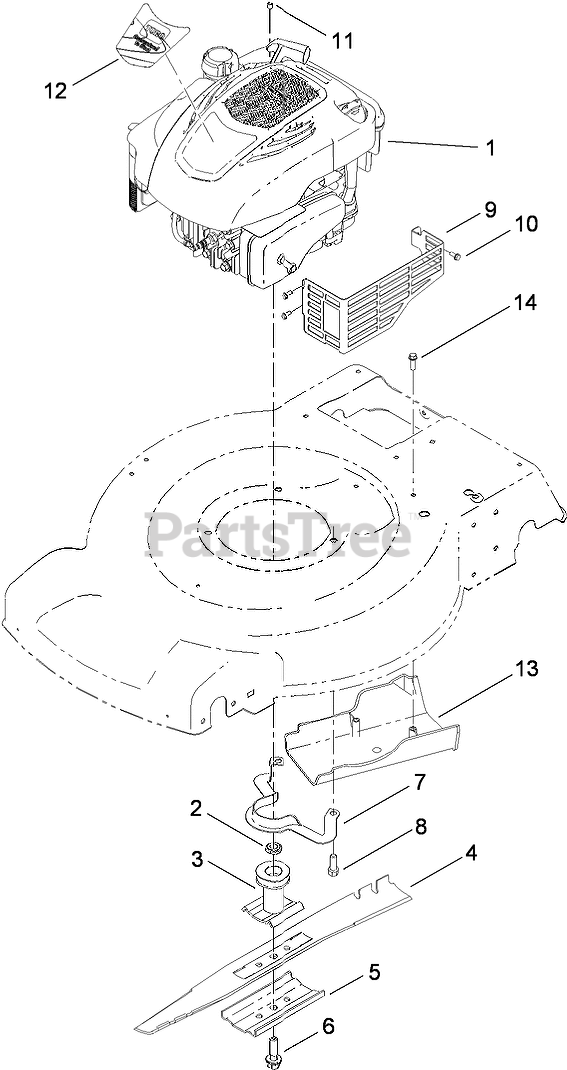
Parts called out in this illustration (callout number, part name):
2	Spacer-Driver
3	DRIVER-BLADE
4	BLADE-22 INCH
5	SUPPORT-BLADE
6	BOLT-BLADE
7	Guide-Belt
8	SCREW-TAPTITE
9	SHIELD-MUFFLER
10	SCREW-TAPTITE
11	STOP-ROPE
12	DECAL-SHROUD
13	COVER-BELT
14	SCREW-HWH
